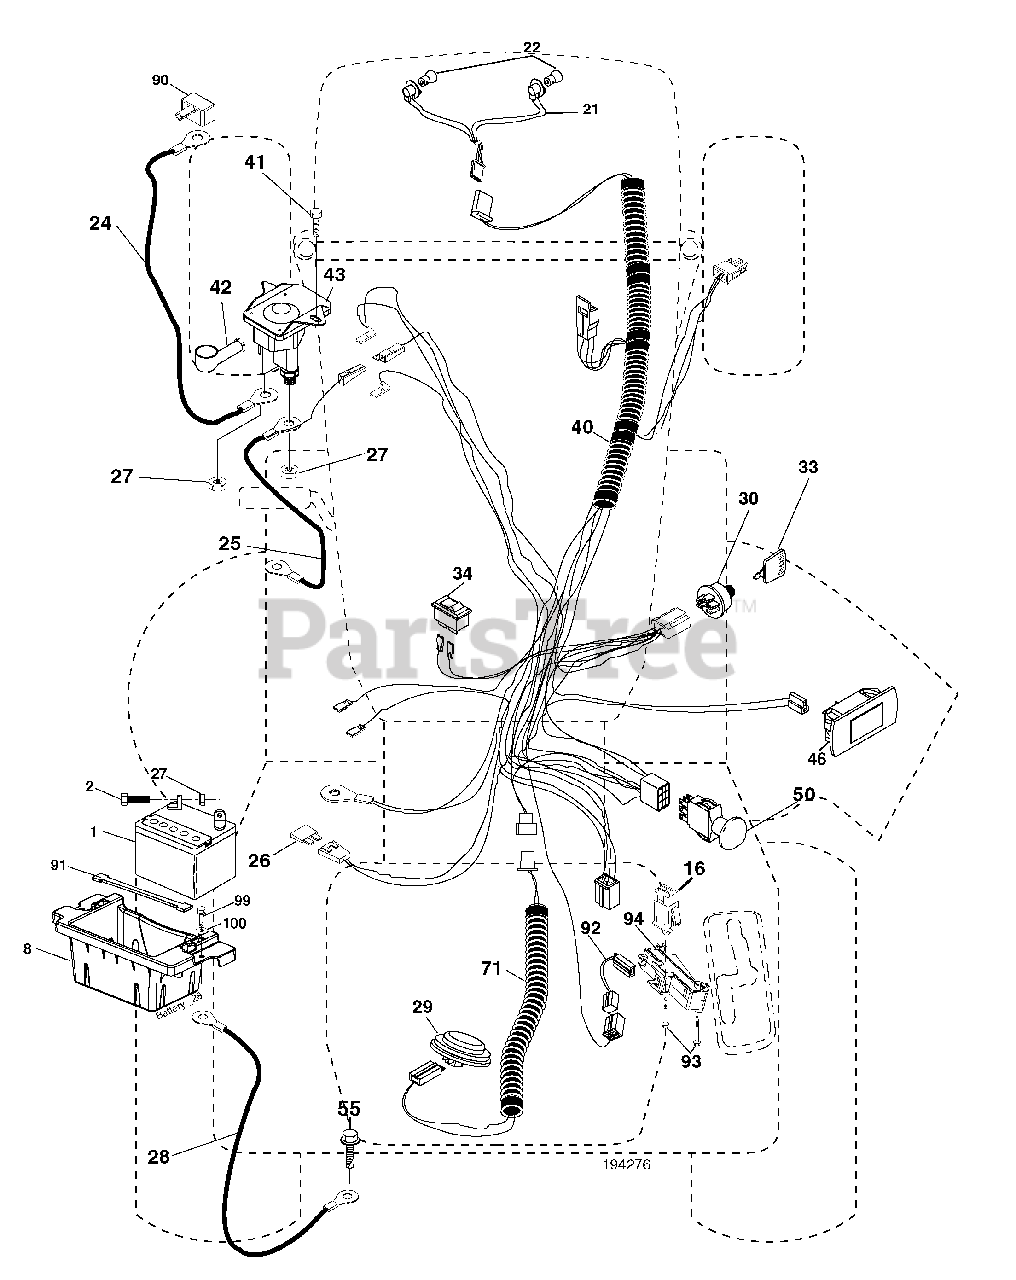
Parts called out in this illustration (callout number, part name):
1	Battery
2	Bolt Hex Head 1/4-20 x 3/4
8	Box Battery
16	Switch Interlock Push-In
21	Harness Socket Light W/4152J
22	Bulb Light
24	Cable Battery
25	Cable Starter
26	Fuse
27	Nut Keps Hex 1/4-20 unc
28	Cable, Ground
29	Switch, Seat
30	Switch, Ign
33	Key, Ignition
34	Switch Light / Reset
40	Harness Ign.
41	Screw Thd Cut 1/4-20 x 1/2
42	Cover, Terminal
43	Solenoid
46	Gauge Hourmeter
50	Switch PTO
55	Screw Thdrol 5/16-18 x 3/4 TYTT
71	Harness Ign. Dash
90	Cover Terminal Battery
91	Strap Battery Mount Front
92	Harness Pigtail
93	Screw Plastite 10-14 x 2.0
94	Module Reverse ROS
99	Screw Hexwsh Thdrol 1/4-20 x 3/4
100	Washer 9/32 x 7/8 x 16 Ga.
